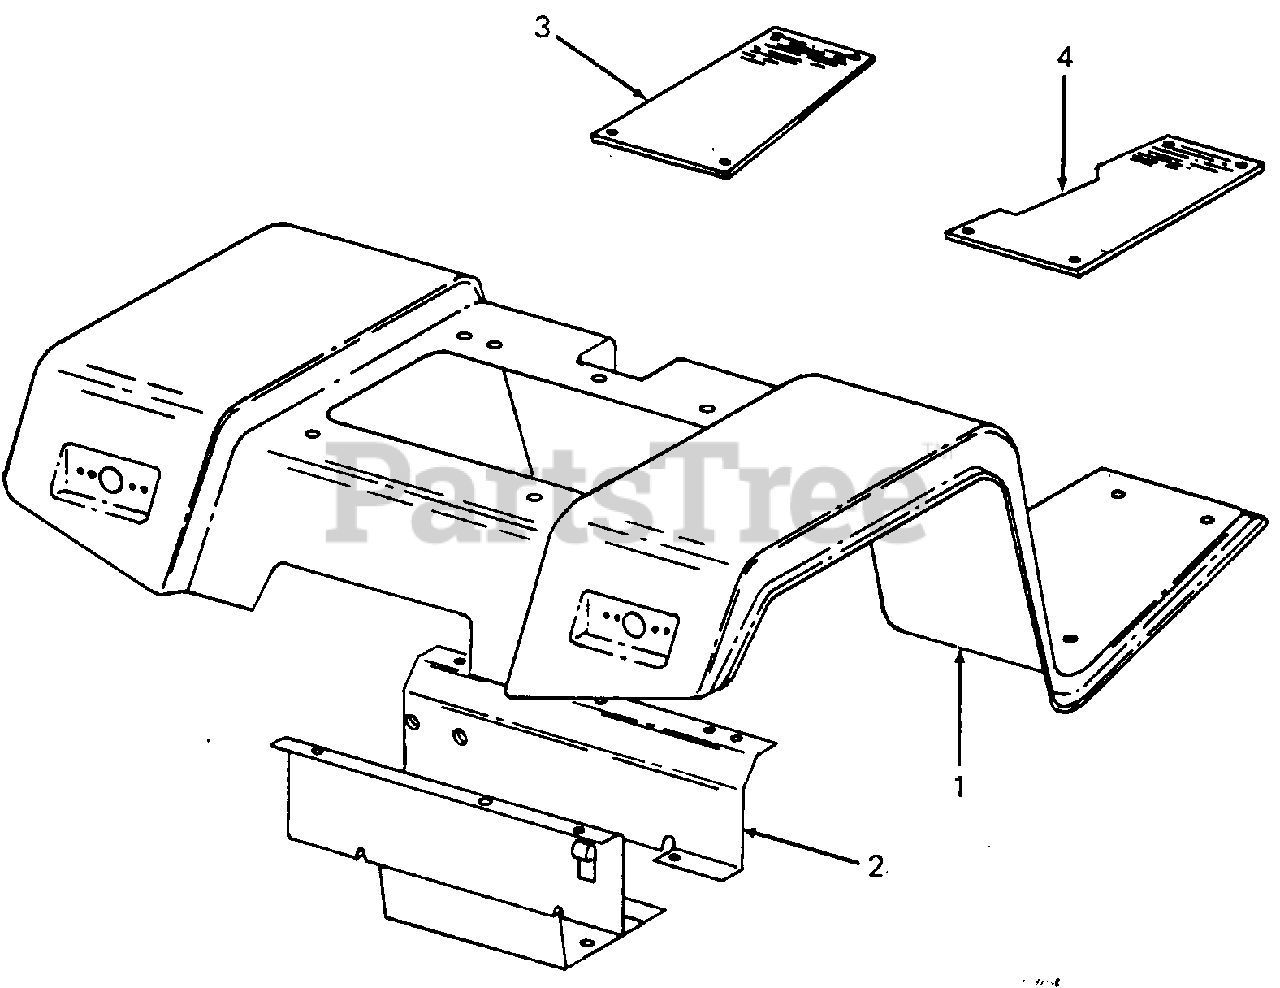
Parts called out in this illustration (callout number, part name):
2	Support, Fender
3	Pad, LH - Foot
4	Pad, RH - Foot
